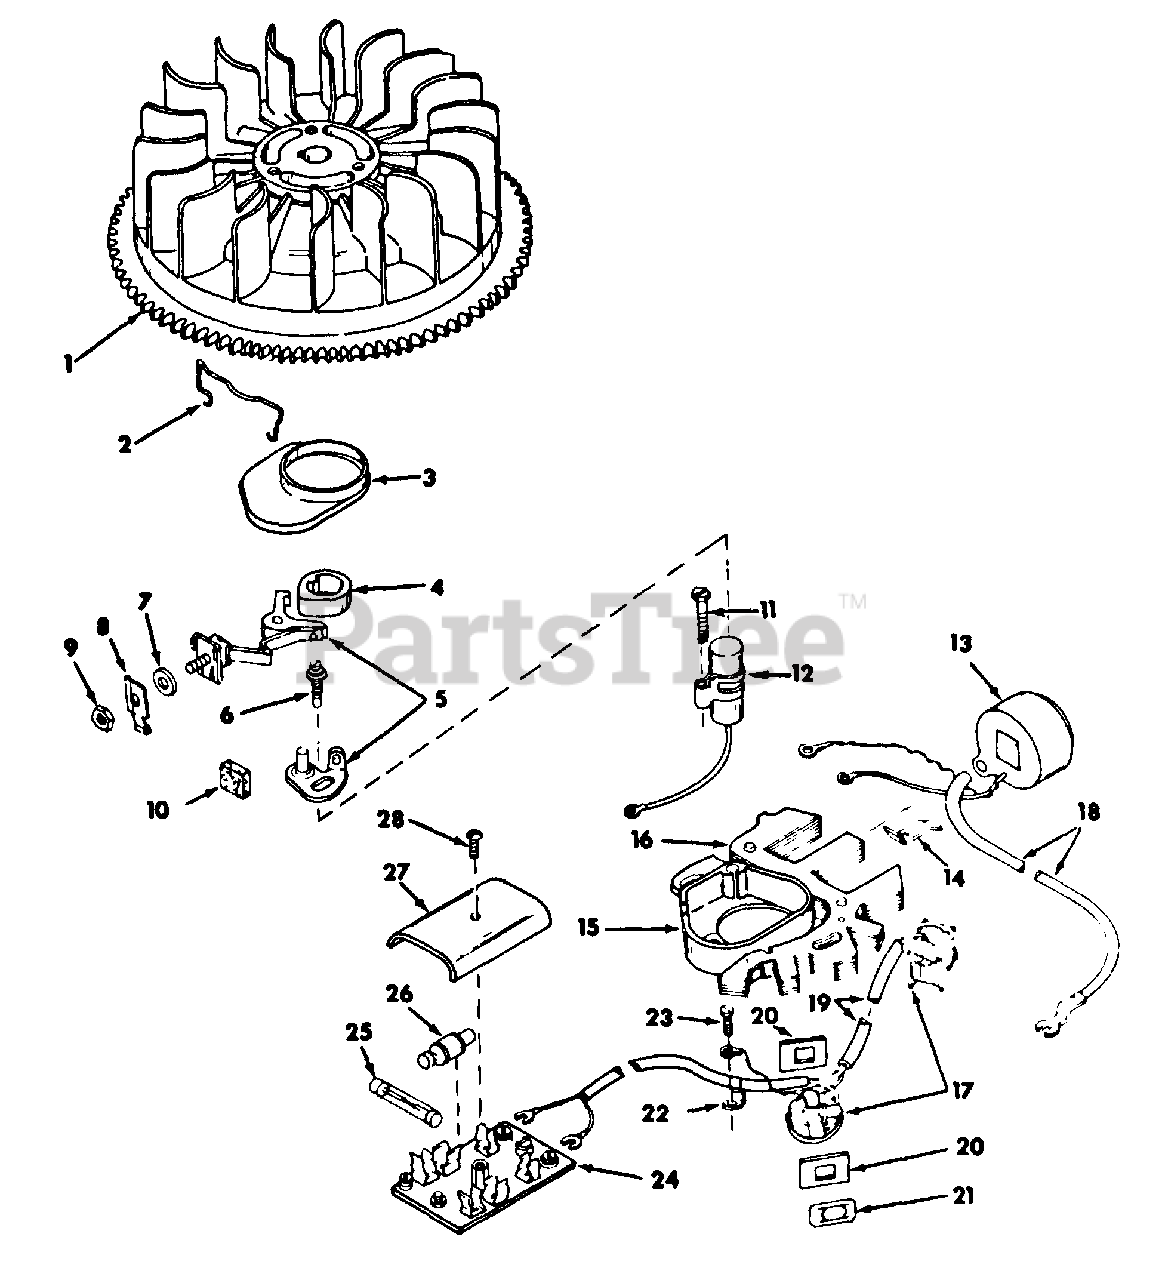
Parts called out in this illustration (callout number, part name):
1	FLYWHEEL
2	SPRING, DUST COVER
3	COVER, BREAKER DUST
4	CAM, BREAKER
5	CONTACT ASSY, BREAKER
6	SCREW AND WASHER BREAKER
7	WASHER, NO. 8 C-Z HV. LOCK
8	TAB, GROUND TERMINAL
9	NUT, 8-32 C-Z HEX. MACH SCREW
10	FELT, CAM WIPER
11	SCREW, 8-32 X 13/16 C-Z TYPE F SLT-HEX,
12	CONDENSER
13	COIL ASSY
14	CLIP, COIL WEDGE SPRING
15	STATOR ASSY
16	CORE AND PLATE
17	GENERATOR COILS AND LEADS
18	WIRE, LEAD
19	SLEEVE, INSULATION
20	SHIELD, COIL
21	CLIP, COIL FASTENING
22	CLIP, GROUND
23	SCREW, GROUND
24	PLATE, RECTIFIER
25	FUSE, 3AG 6 AMPERES
27	COVER, PANEL
28	SCREW, 5-40 X 3/8 C-Z CR-REC-RD-HD MACH
